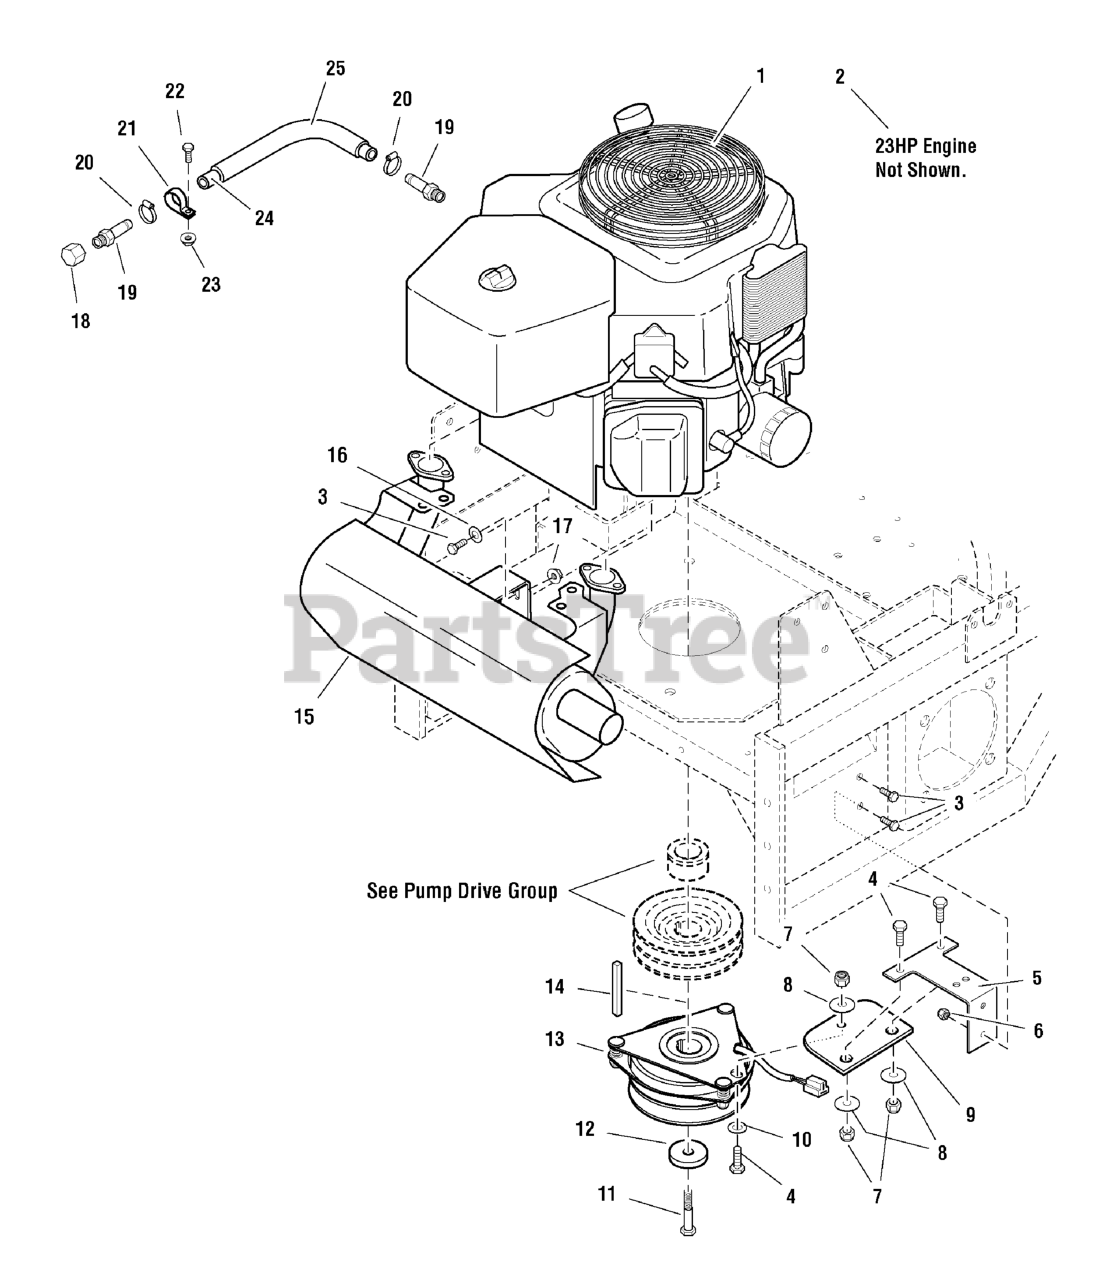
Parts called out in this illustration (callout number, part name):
1	ENGINE, Kohler
3	BOLT, 5/16-18 X 3/4 GD5
4	BOLT, 3/8-16 X 1" GD5 CZ
5	CLUTCH ANCHOR
6	NUT, 5/16-18 Hex Nylon Lock
7	NUT, 3/8-16 HEX NYLON LOCK
8	WASHER, 3/8" Fender
9	CLUTCH ANCHOR PAD
10	WASHER, 3/8 SAE
11	CRANKSHAFT BOLT, 7/16 x 2
12	SPACER, .45 x 1.88 x .38
13	ELECTRIC CLUTCH
14	KEY, 1/4 SQ. X 3-1/2
15	MUFFLER
16	WASHER, 5/16" SAE
17	NUT, 5/16-18 HEX SERRATED FLANGE (SMALL)
18	CAP, 3/8 NPT
19	FITTING, 3/8NPT-1/2" Hose, Straight
20	CLAMP, #6 Hose
21	CLAMP, Vinyl
22	BOLT, 1/4-20 x 3/4
23	NUT, 1/4-20 HEX SERR. FLANGE
24	HOSE, 13"
25	WIRE LOOM, 12"
